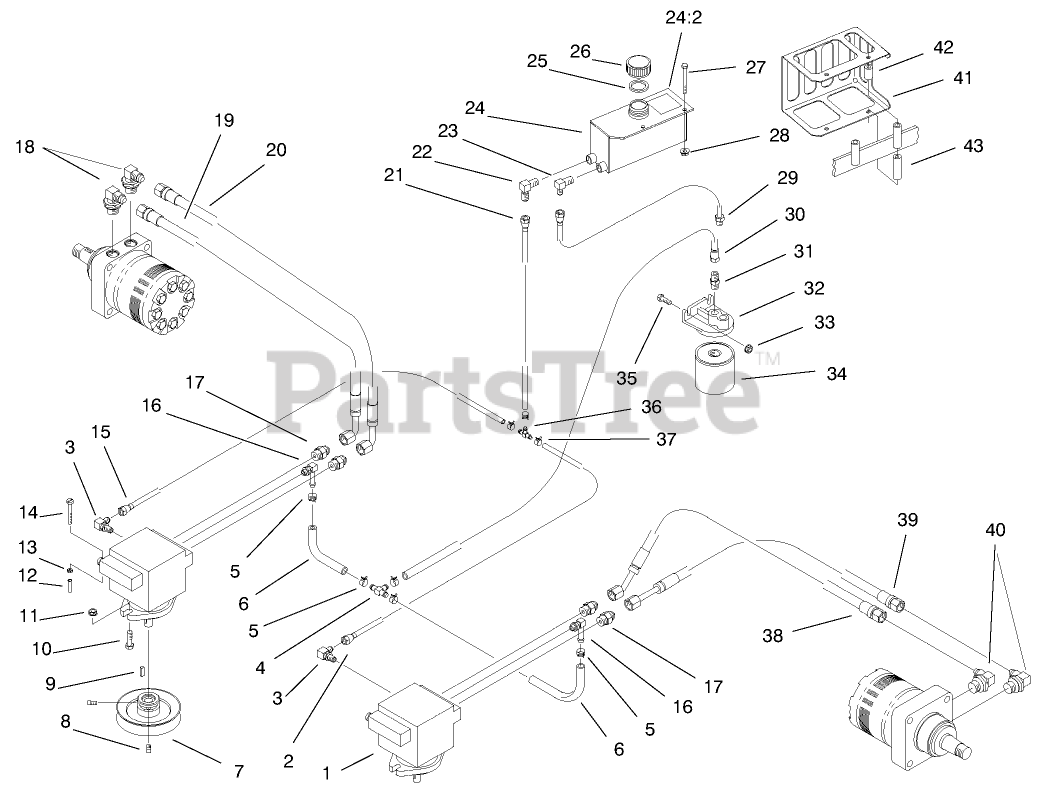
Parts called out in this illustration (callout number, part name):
1	Pump-Hydro
2	Hose-Low Pressure
3	Elbow
4	Fitting
5	Clamp-Hose
6	Hose-Low Pressure
7	Sheave w/Hub
8	SCREW-SET, SQH
9	Key
10	SCREW-HH
11	NUT-HHF, WHIZ
12	Grip
13	NUT-LOCK, NI
14	Screw-PPH
15	Hose-Low Pressure
16	Elbow
17	Adapter
18	Elbow 90
19	HOSE-FRONT
20	HOSE-REAR
21	Hose
22	Elbow
23	Elbow
24	HYDRAULIC TANK ASM
24:2	DECAL-HOT SURFACE
25	Gasket
26	Cap
27	Screw-HH
28	NUT-HF
29	Hose
30	Hose
31	Connector
32	Head-Filter
33	NUT-HF
34	Filter-Hydro
34	Filter-Winter
35	SCREW-HH
36	Fitting
37	Clamp-Hose
38	HOSE-REAR
39	HOSE-LH
40	Elbow
41	SHIELD-HEAT, HYDRO RES
42	SPACER
43	SPACER
